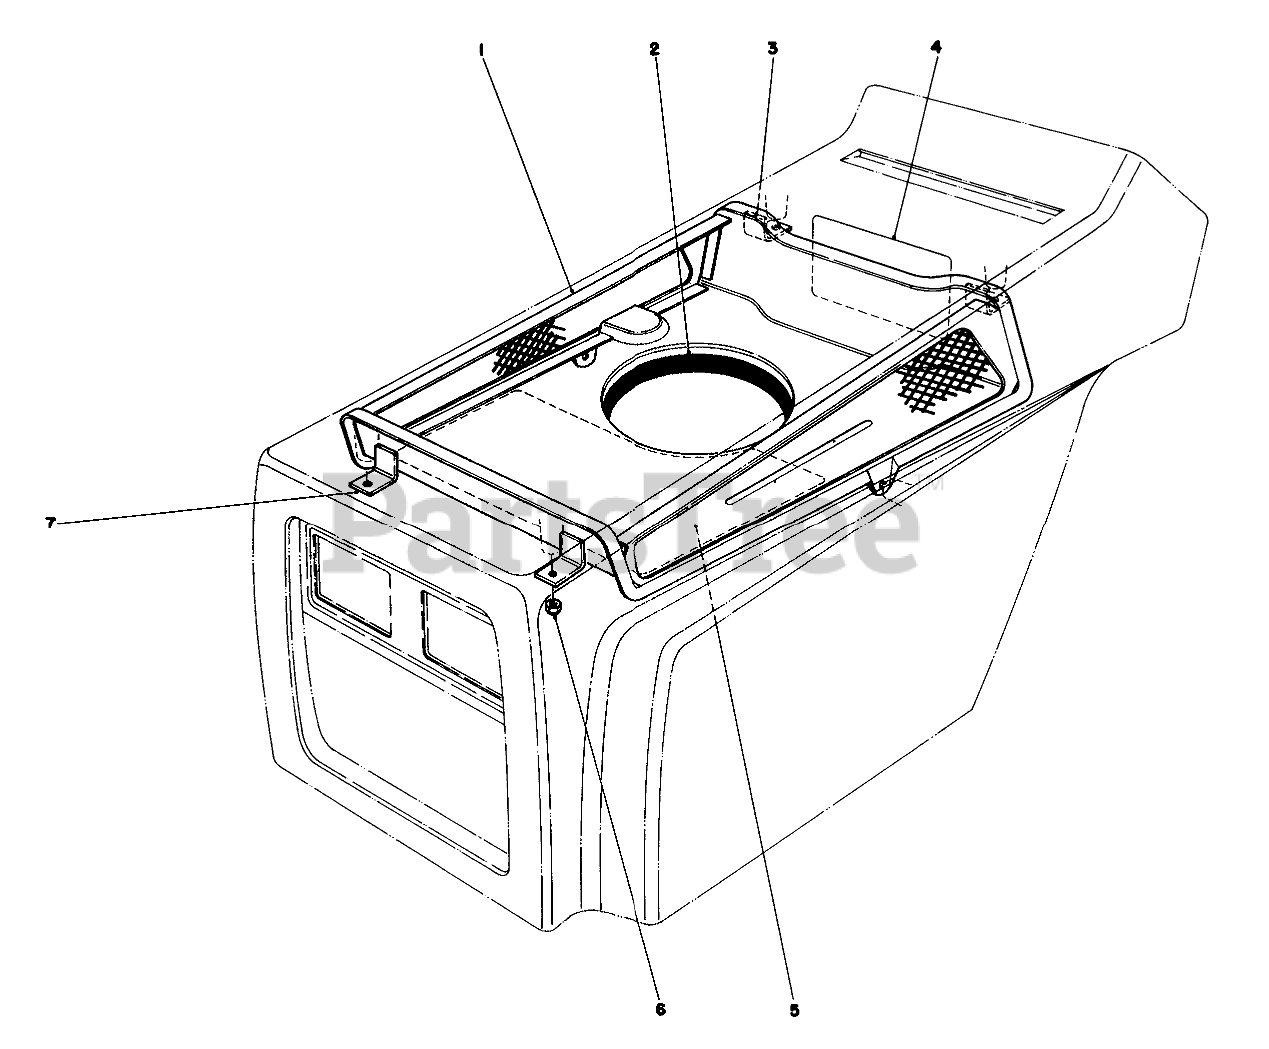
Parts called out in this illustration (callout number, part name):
1	Duct Hood
2	Seal Engine
3	Bracket Rear Duct Support
4	Decal-Belt Change
5	Decal Service
6	NUT-LOCK, CONE
7	Bracket Duct Support
